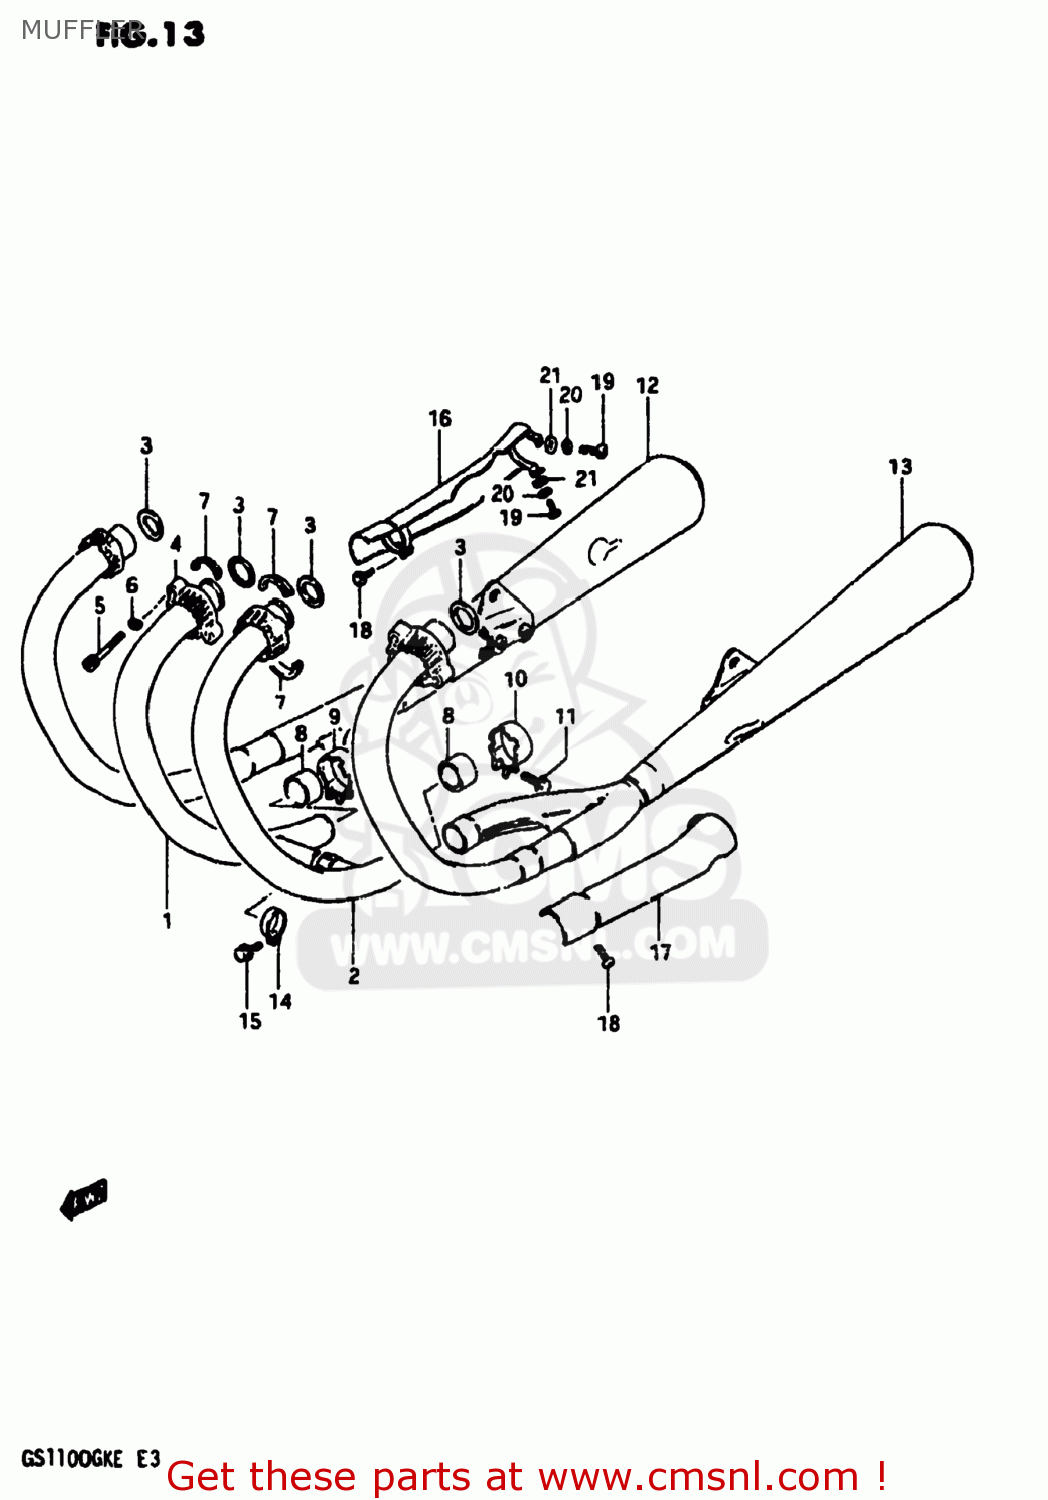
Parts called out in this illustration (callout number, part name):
1	PIPE,EXHAUST,CENTER,RIGHT
2	PIPE,EXHAUST,CENTER,LEFT
3	GASKET,EXHAUST PIPE (NAS)
4	CLAMP(H:21)
5	BOLT
6	LOCK WASHER
7	PLATE,EXHAUST
8	CONNECTOR,MUFFLER
9	CLAMP,MUFFLER CONNECTOR,R
10	CLAMP,MUFFLER CONNECTOR,L
11	BOLT
12	MUFFLER ASSEMBLY,RIGHT
13	MUFFLER ASSEMBLY,LEFT
14	CLAMP
15	BOLT
16	COVER,MUFFLER,RIGHT
17	COVER,MUFFLER,LEFT
18	SCREW
19	SCREW
20	LOCK WASHER
21	WASHER
